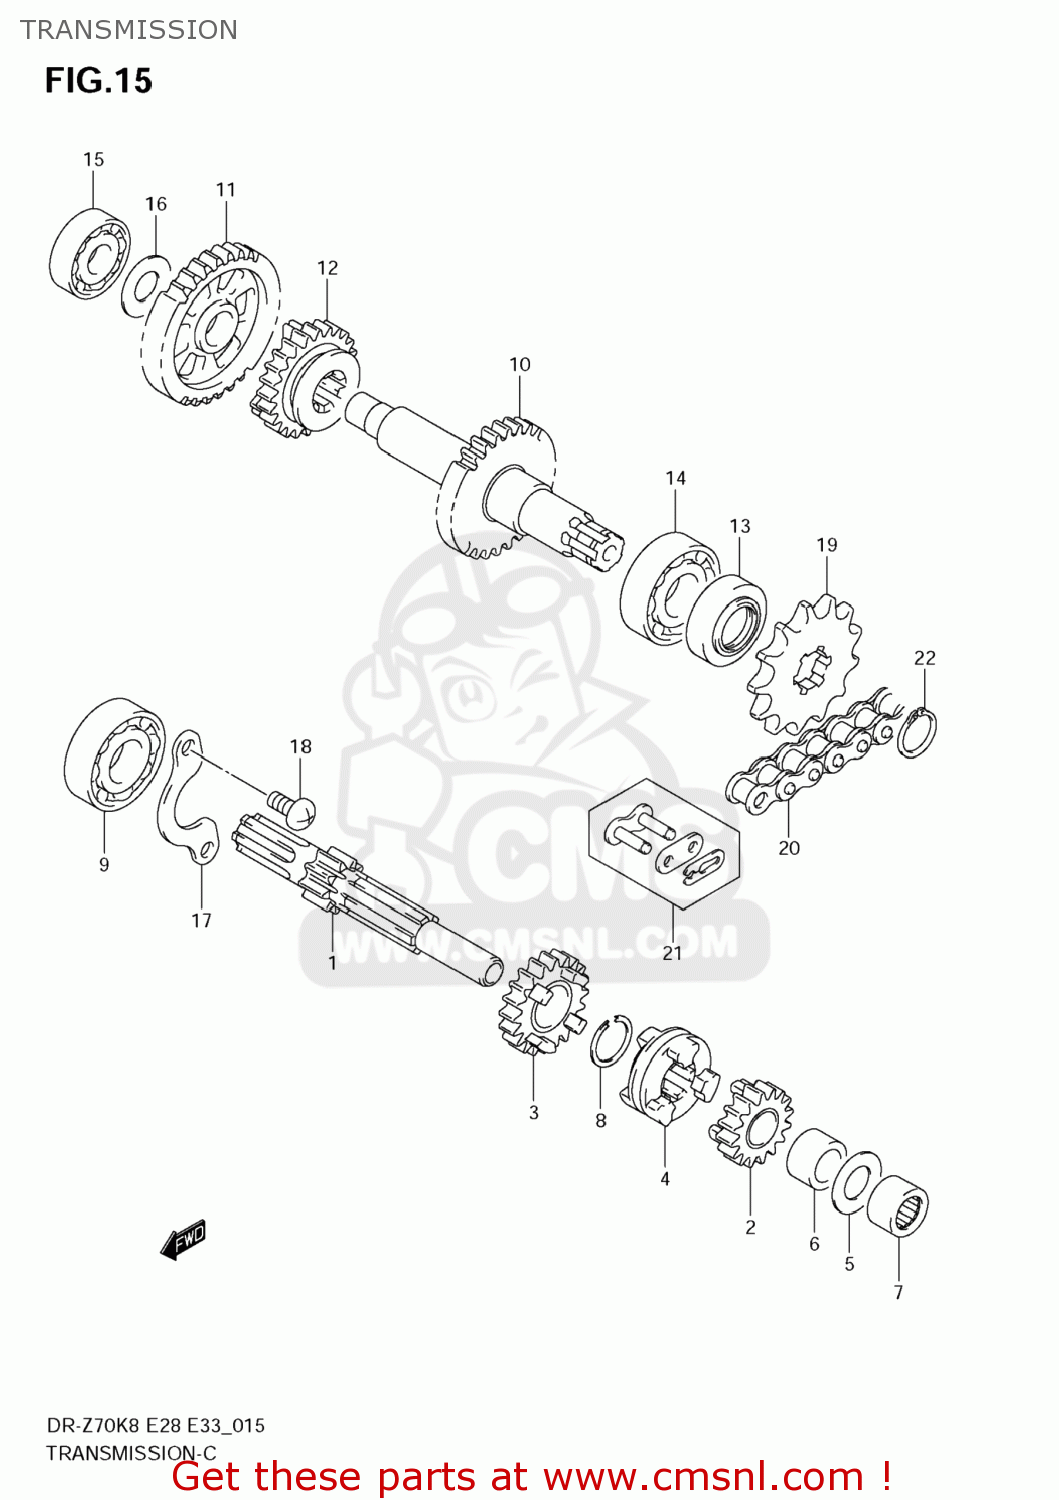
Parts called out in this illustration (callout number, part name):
1	SHAFT,COUNTER(NT:10)
2	GEAR,2ND DRIVE(NT:16)
3	GEAR,3RD DRIVE(NT:20)
4	WHEEL,SLIDING DOG
5	WASHER(13X24X1)
6	SPACER(13X19X12.5)
7	BEARING(13X19X12)
8	CIRCLIP
9	BEARING
10	SHAFT,DRIVE(NT:29)
11	GEAR,1ST DRIVEN(NT:34)
12	GEAR,3RD DRIVEN(NT:24)
13	SEAL,OIL(17X30X7)
14	BEARING
15	BEARING
16	WASHER
17	RETAINER,BEARING
18	BOLT(6X12)
19	SPROCKET,ENGINE(NT:13)
20	CHAIN,DRIVE(DID428)
21	JOINT,CHAIN
22	CIRCLIP 16MM
